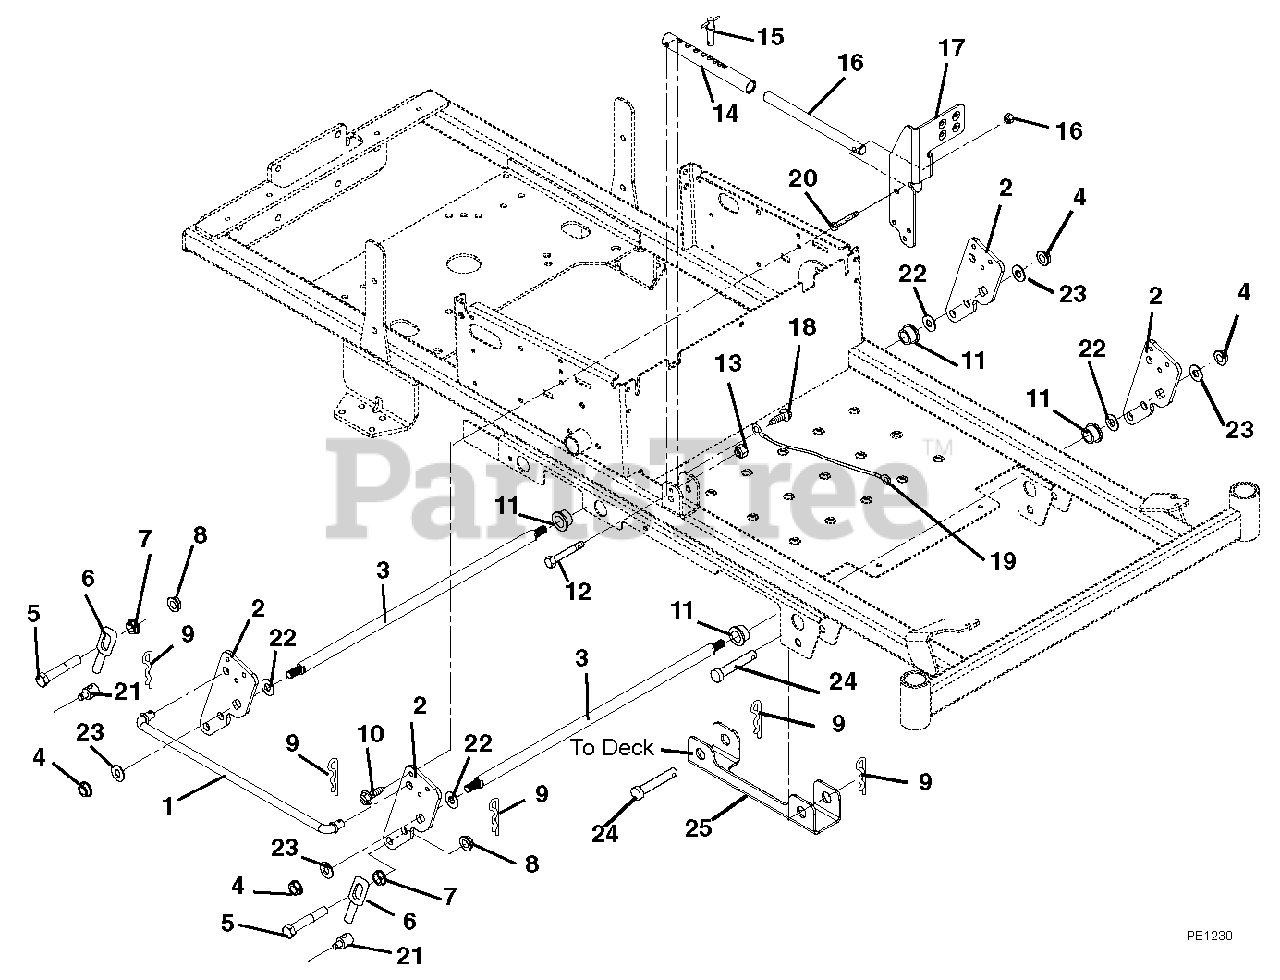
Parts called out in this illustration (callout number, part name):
1	Rod, Lift
2	Lift Arm
3	Shaft, Lift
4	Nut, Hex .250-28
5	Bolt, Hex .50-13 x 2.75 Grade 8
6	Deck Link
7	Nut, Spin Lock Flange .50-13
8	Nut .50-13 Nyloc Flange
9	Pin, Hair #16
10	Screw, Tap .31-18 x .50
11	Bushing, Flange .750 x 1.000 x .625 x 1.250
12	Bolt, Hex .38-16 x 2.00 Grade 5
13	Nut, Flange Nyloc 3/8-16
14	Tube, Lift Stop
15	Pin, Spring Ball .375OD x 1.50
16	Rod, Lift
17	Pedal, Foot Lift
18	Screw, Tap .25-20 x .50
19	Cable, Hood
20	Bolt, Hex .38-16 x 2.50 Grade 5
21	Trunnion
22	Washer, Flat Steel .755 x 1.375 x .062
23	Washer, Flat-Steel .515 x 1.625 x .250
24	Pin-Clevis .494 x 2.50
25	Channel, Deck Lift
